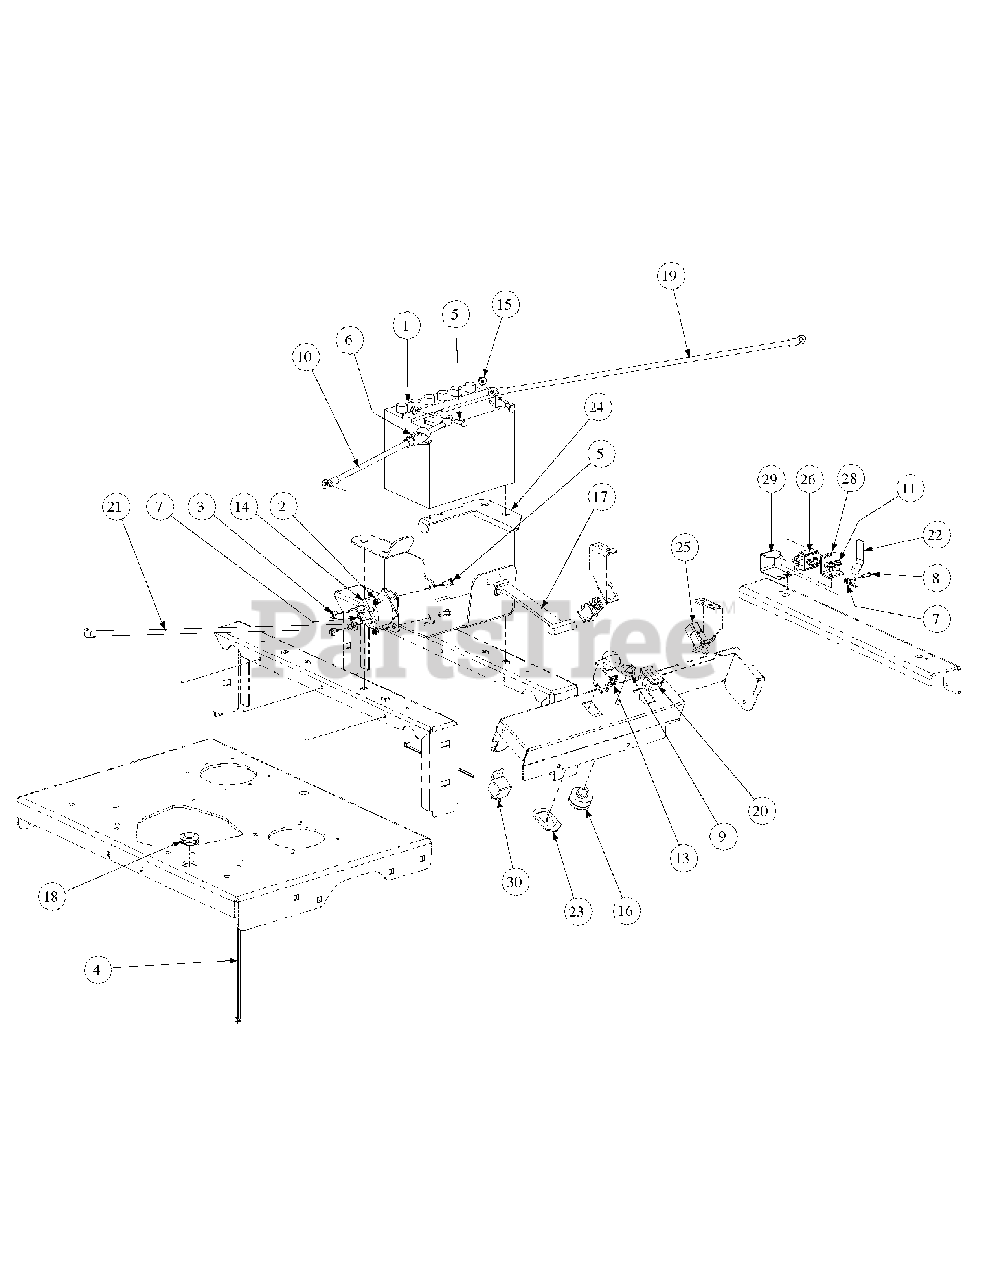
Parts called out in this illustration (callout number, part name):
1	Battery, 12V 225CCA 30 Min
2	Lock Nut w/Nylon Insert
3	Nylock Nut, 5/16-18
4	Tie, Cable, 3/16 x .05 x 7.4"
5	Screw, Hex, Cap, 1/4-20 x .75
6	Boot, 1" OD Rubber Battery-PST, Red
7	Nut, Lock, Nylon Insert, #10-32
8	Screw, Phillips Head, Machine, 10-32 x 5/8
9	Nut, W/Cap, 5/8-32 Ignition
10	Cable, Battery, Red, 15"
11	Screw, TT, 1/4-20, 0.5, Hex Index Washer
12	Hourmeter, Harness
13	Switch, Electric, PTO
14	Solenoid Magnetic Switch
15	Hex Flange Lock Nut, 1/4-20
16	Switch, Ignition, 6 Pin
17	Strap, Battery
18	Grommet, .75 ID
19	Cable, Battery Black, 28"
20	Meter, Hour
21	Cable, Battery Red, 32"
22	Spring Retainer
23	Bracket, PTO Switch Retainer
24	Mount Bracket, Battery
25	Switch, Safety N.O./N.C.
26	Switch, Plunger
27	Harness Assembly
28	Bracket, Plunger Switch
29	Clamp, Plunger Switch
30	Relay, 12V 40A
